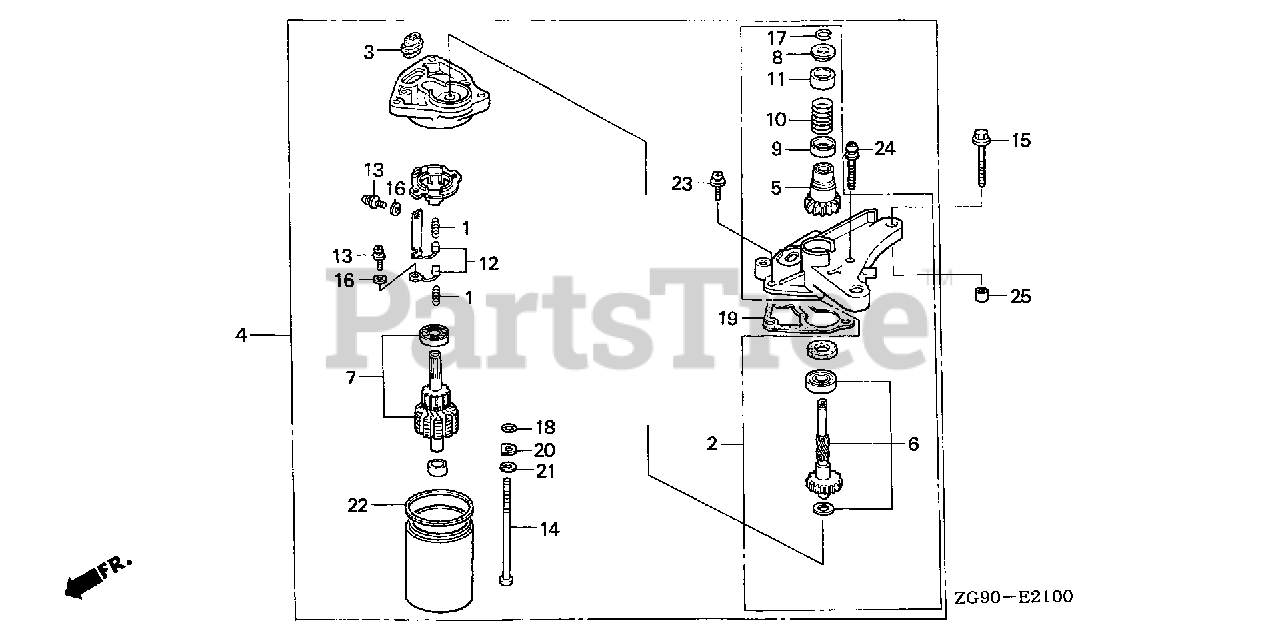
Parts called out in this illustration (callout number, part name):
1	SPRING, BRUSH
2	COVER, GEAR
4	STARTER MOTOR ASSY.
5	GEAR, PINION (16T)
6	SHAFT SET, GEAR
7	ROTOR ASSY.
8	PIECE A, STOPPER
9	PIECE B, STOPPER
10	SPRING, RETURN
11	COVER, SPRING
13	SCREW-WASHER (3X8)
14	BOLT, SETTING
15	BOLT, FLANGE (6X32)
16	WASHER, SPECIAL
17	CIRCLIP (7.1MM)
20	WASHER, SPECIAL
21	WASHER, SPRING
23	SCREW-WASHER (5X16)
24	SCREW-WASHER (5X32)
25	PIN, DOWEL (8X14)
